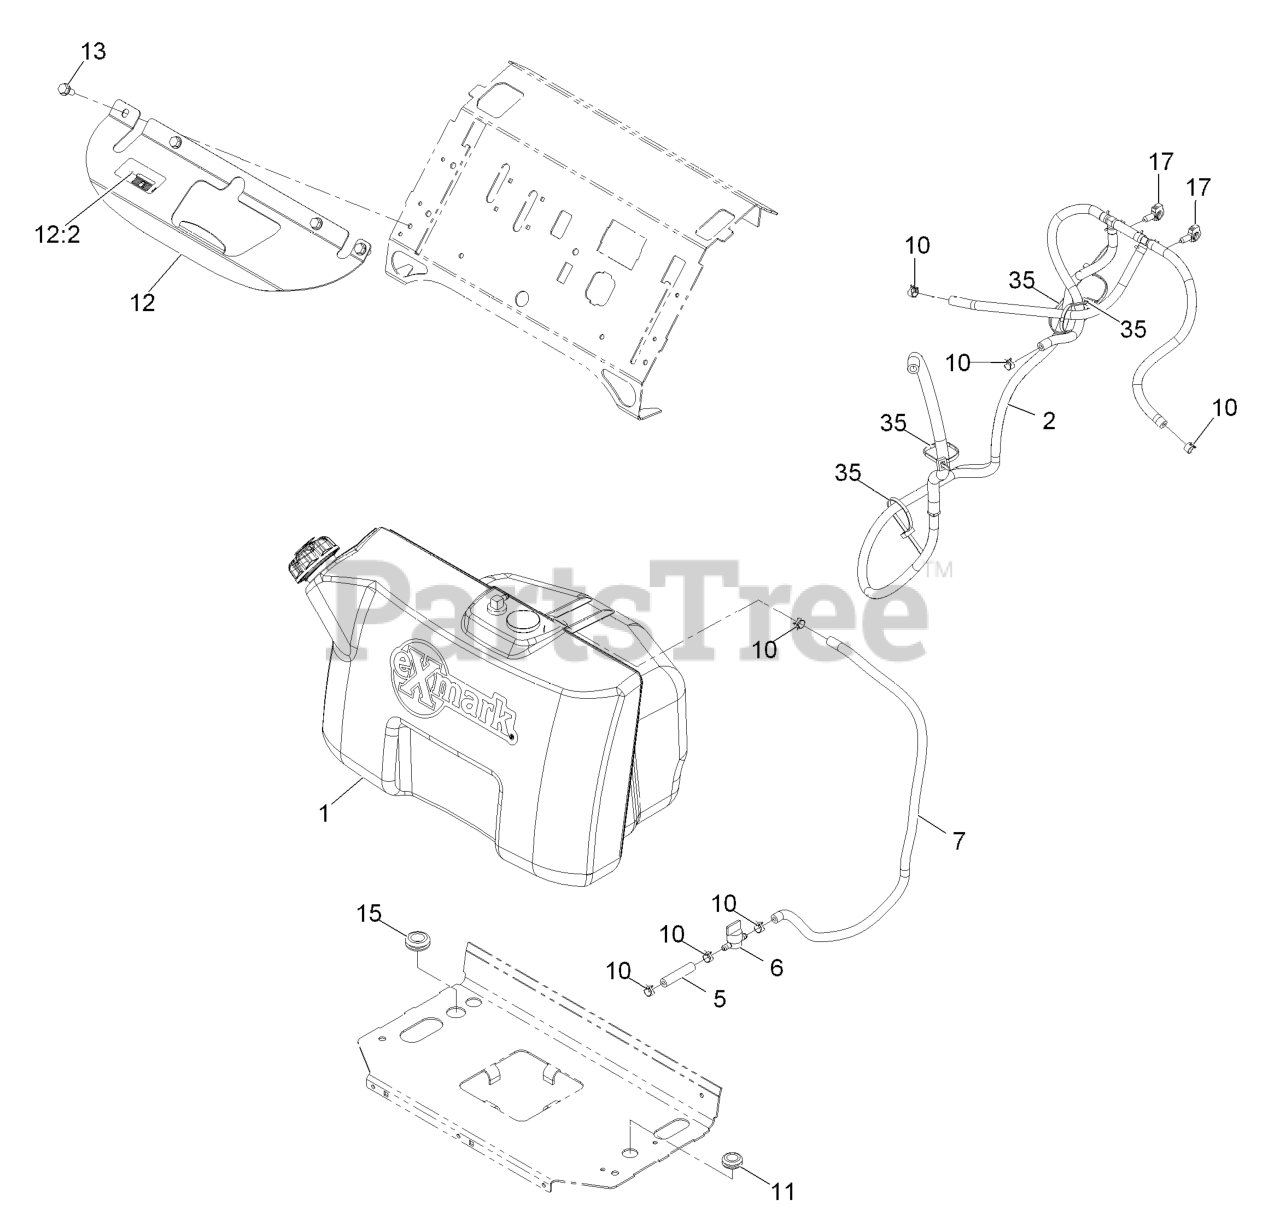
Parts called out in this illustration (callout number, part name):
2	VENT ASM
5	HOSE-FUEL
6	VALVE-FUEL
7	HOSE-FUEL
10	CLAMP-HOSE
11	GROMMET
12	BRACKET-TANK
12:2	DECAL-FILL, FUEL
13	SCREW-THD ROLL, HWH
15	GROMMET
17	CLIP-HARNESS
35	TIE-CABLE
